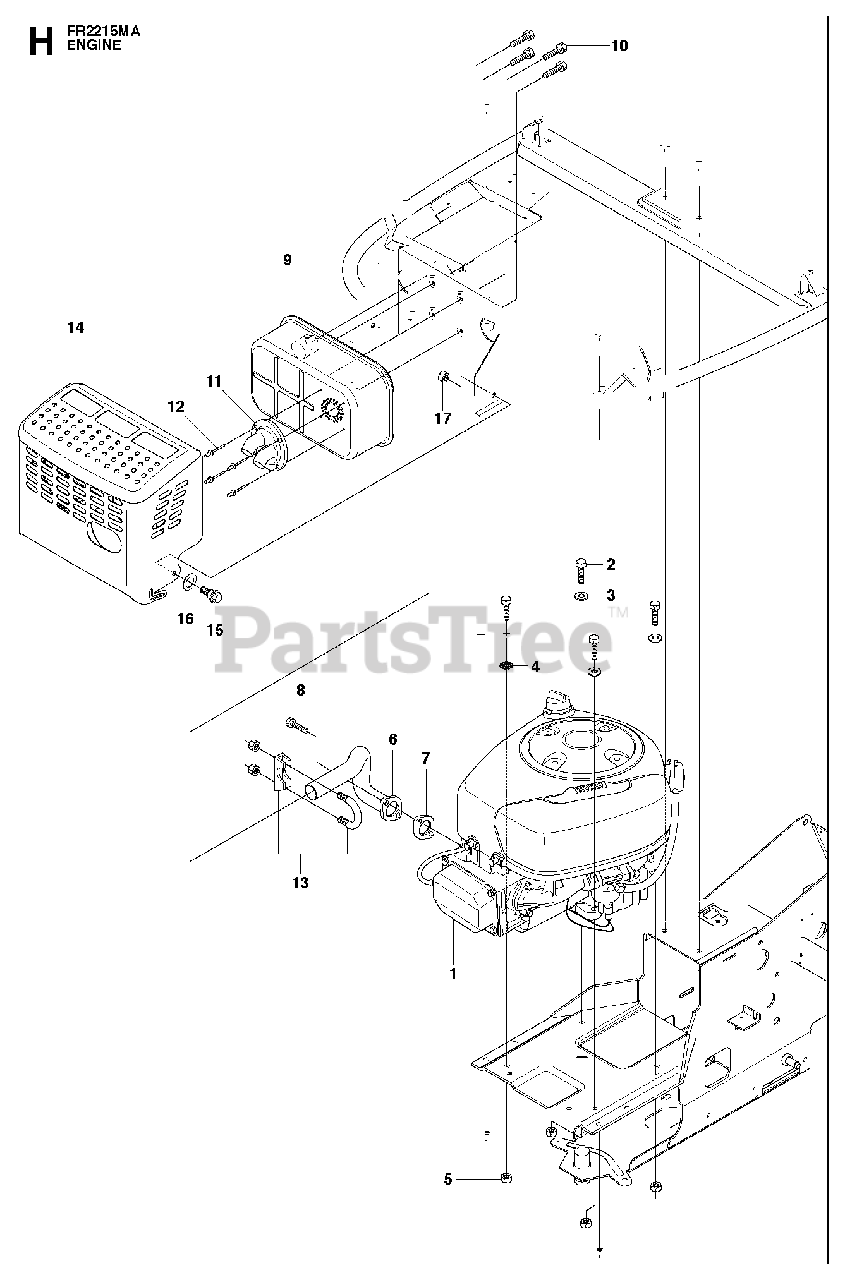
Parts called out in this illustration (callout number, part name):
3	WASHER BRB 8.4X17
5	LOCKNUT M8
9	MUFFLER
16	SPRINGWASHER
17	LOCKNUT M8
